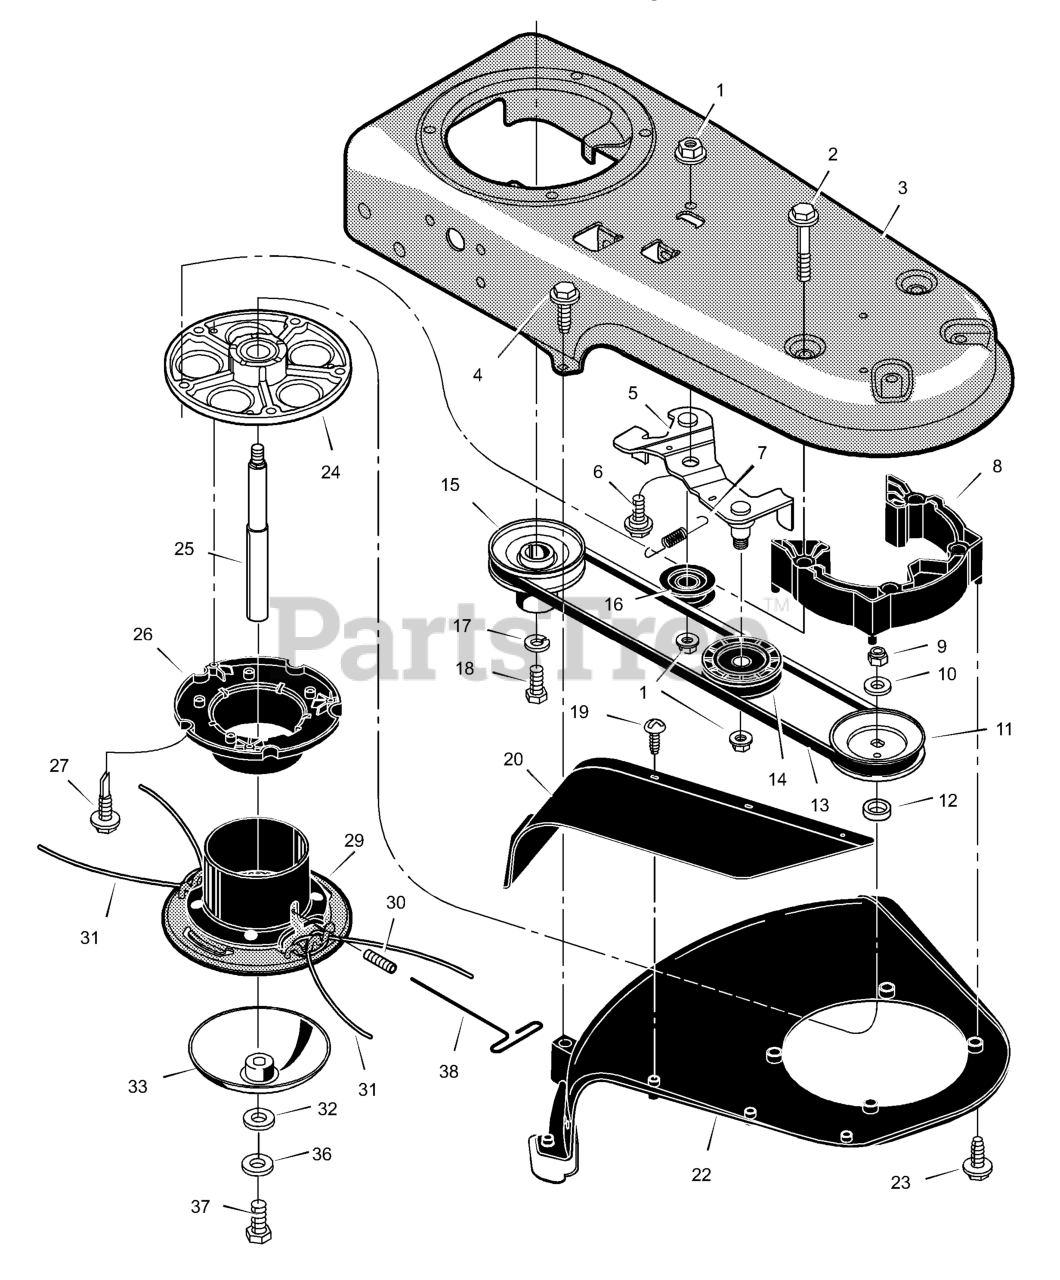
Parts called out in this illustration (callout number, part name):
1	Nut
2	Screw
5	Bracket, Idler Assembly
7	Spring, Extension
8	Spacer Assembly, Jackshaft
10	Washer, Flat
11	Pulley, Cutting Head
12	Spacer, Upper Pulley
13	Belt, Trimmer
14	PULLEY, IDLER, V, 1.88
15	Pulley, Engine
16	Pulley, Idler
17	Lockwasher
20	Flap, Debris
22	Shield, Trimmer
24	Housing, Jackshaft
25	Shaft, Cutting Head
26	Wrap, Weed
29	Assembly, Cutter Head & Wrap
30	Screw, Set
31	Line, Trimmer 0.155 X 21.25
32	Flatwasher
33	Guide, Metal Height
36	Lockwasher
38	Wrench, T-Handle
